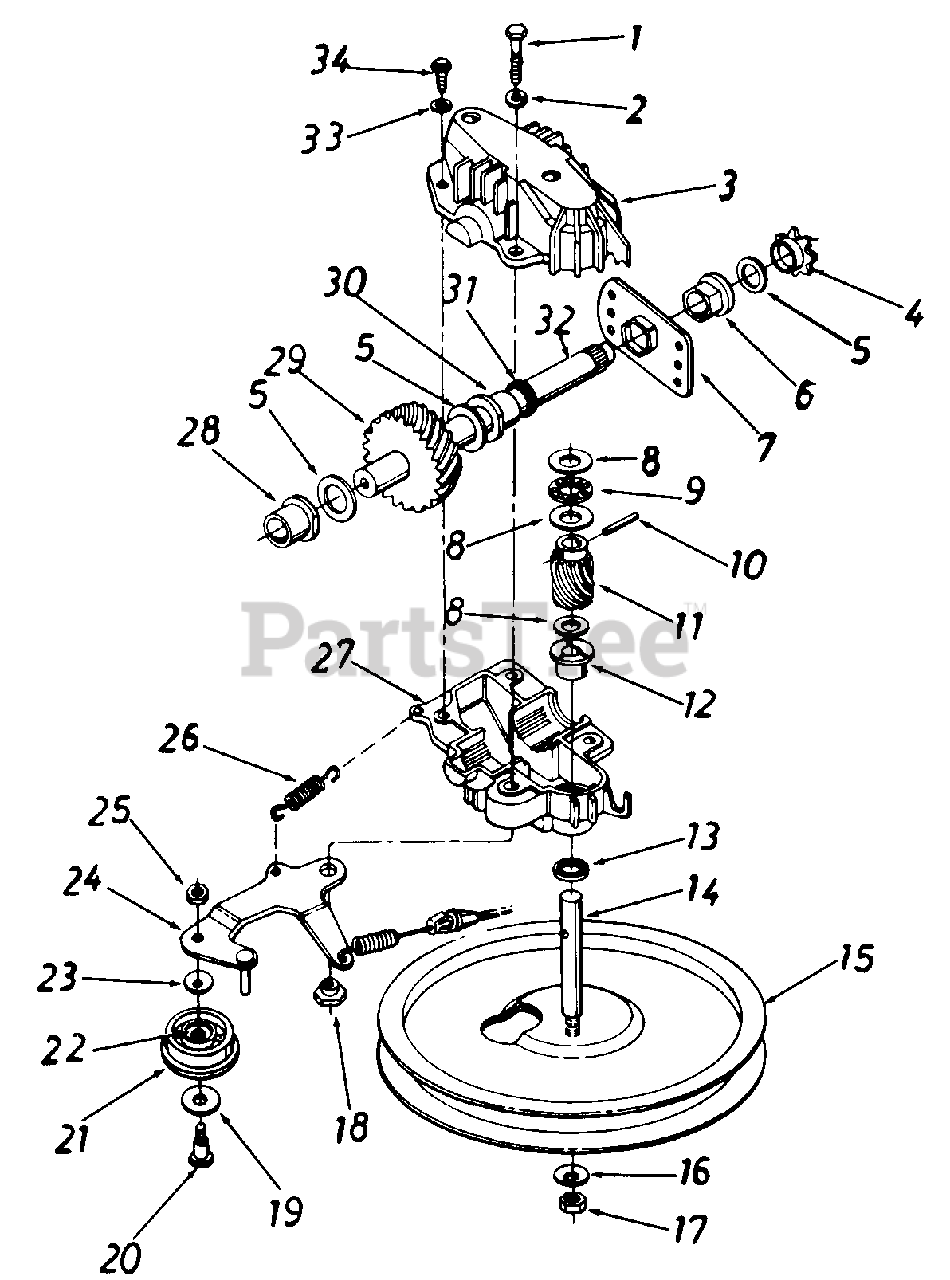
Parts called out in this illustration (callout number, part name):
1	SCREW-HEX 1/4-20 X 1.25
2	LOCK WASHER 1/4 DIA
3	HOUSING HALF-UPPER
4	SPROCKET-7T
5	WASHER-FL
6	BEARING-HEX FLANGE
7	BEARING-CUP HEX
8	WASHER-THRUST.382 X .684
9	BEARING-THRUST
10	PIN-SPRING-SPIR 1/8 X .625
11	GEAR-WORM
12	BEARING-FLANGE
13	SEAL-OIL-.375 ID
14	KIT-TRAN PUL SHFT
15	PULLEY
16	WASHER-SPRING BELL
17	NUT-HEX CENTER L-1/4-20
18	SPACER-SHLD
19	WASHER-FL .995 X .032
20	SCREW-SHLD
21	KIT-PULLEY
22	BEARING-NEEDLE
23	WASHER-SPRING BELL
24	BRACKET ASSY-IDLER
25	NUT-HEX CENTER L-1/4-20
26	SPRING-EXTENSION
27	HOUSING HALF-LOWER
28	BEARING-FLANGE
29	SHAFT-ASSY W/GEAR
30	BEARING-FLANGE
32	SHAFT-ASSY W/GEAR
33	WASHER-LOCK-#10
34	SCREW-HEX WASH HD TAP
